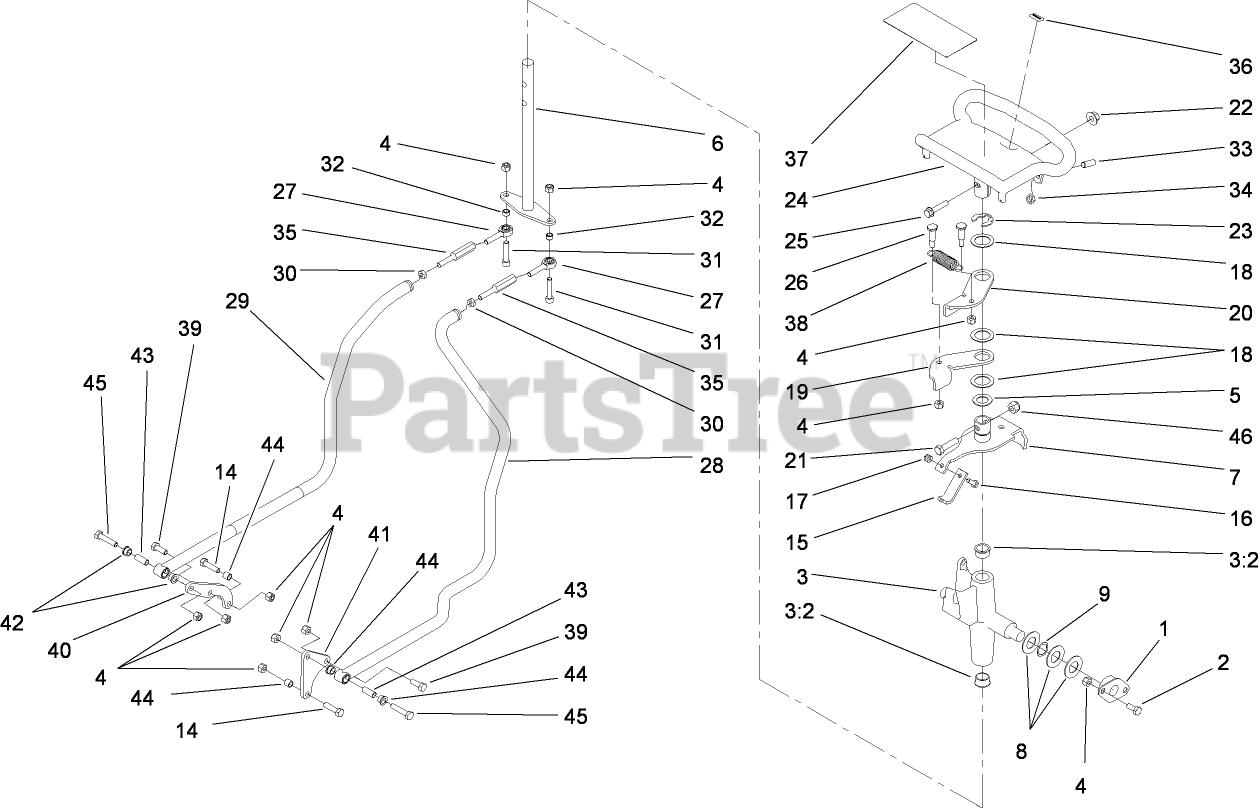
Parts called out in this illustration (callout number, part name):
1	BUSHING
2	SCREW-HH
3	CONTROL SUPPORT ASM
3:2	BEARING-FLANGE
4	NUT-LOCK, NI
5	WASHER-THRUST
6	DRIVE ROD ASM
7	LEVER-PIVOT
8	WASHER-FLAT
9	WASHER-SPRING, WAVE
14	SCREW-HH
15	PLATE-NEUTRAL
16	SCREW-HH
17	NUT-LOCK, NI
18	WASHER-PLAIN
19	LEVER-RETURN, RH
20	LEVER-RETURN, LH
21	SCREW-HH
22	NUT-FLANGE
23	RING-RETAINING
24	HANDLE-CONTROL
25	SCREW-HHF
26	SCREW-SHOULDER
27	BEARING-ROD END, LH
28	ROD-CONTROL, LH
29	ROD-CONTROL, RH
30	NUT-JAM
31	SCREW-HSH
32	SPACER-LEVER, TRACTION
33	SCREW-SET
34	NUT-JAM
35	LINK-CONTROL
36	DECAL
37	DECAL-TRACTION
38	SPRING-EXTENSION
39	SCREW-HH
40	PLATE-ADAPTER, CONTROL, RH
41	PLATE-ADAPTER, CONTROL, LH
42	BUSHING-FLANGED
43	SPACER
44	SPACER
45	SCREW-HH
46	NUT-LOCK, NI
